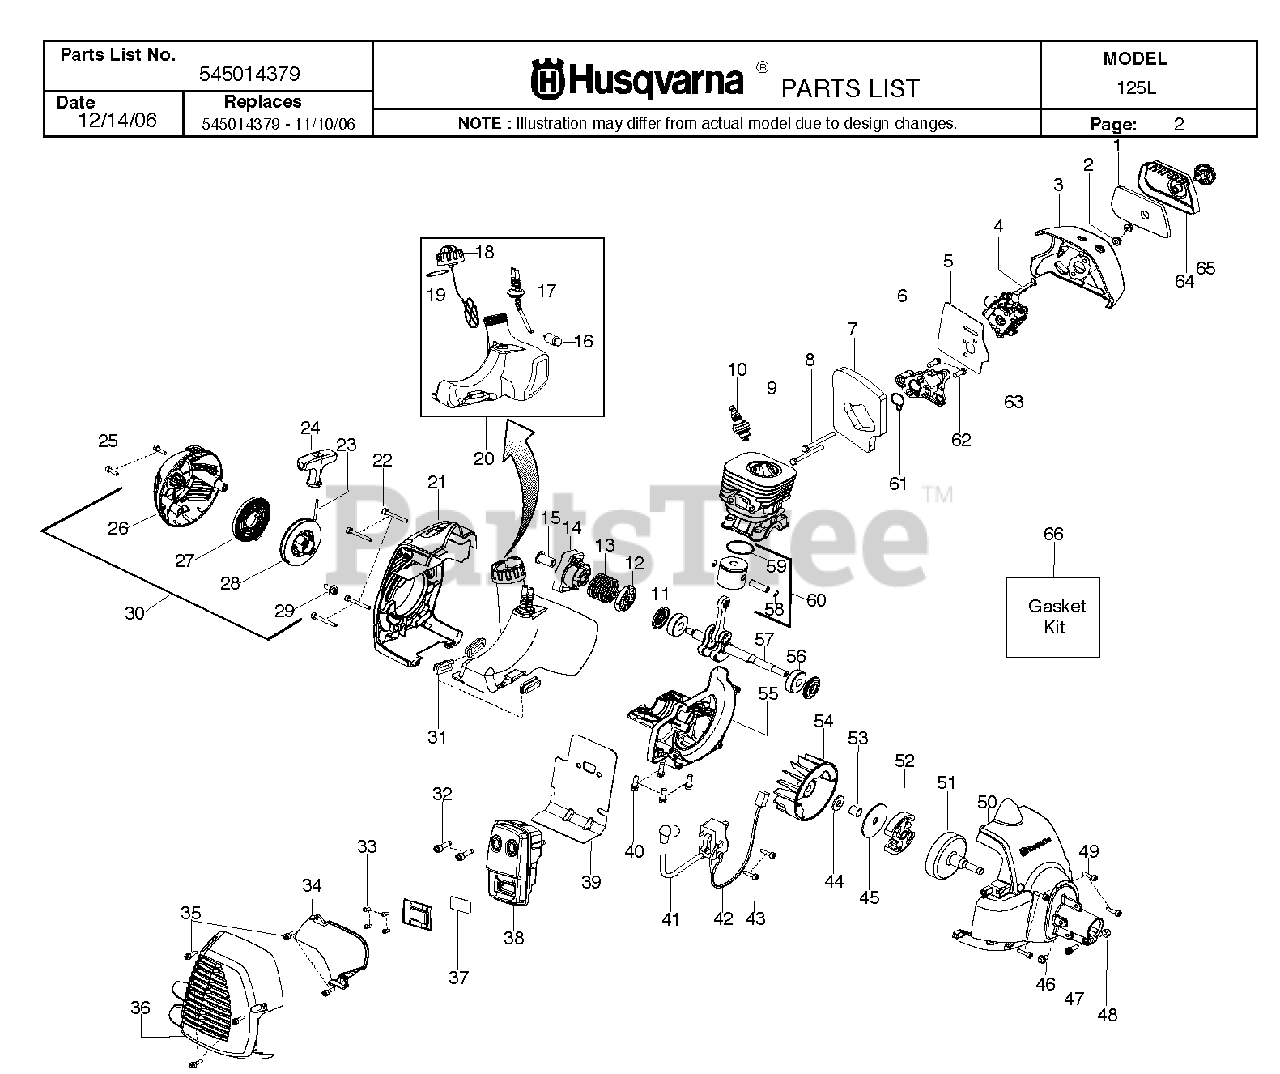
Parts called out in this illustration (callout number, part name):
2	Nut-Carb. Screw
3	Air Box
4	Lever - Choke
5	Kit-Carb. Gasket
6	Adaptor-Carb.
7	Kit-Gasket
9	Cylinder
10	Plug-Spark
11	Kit-Crankshaft seal
12	Washer-Starter
13	Spring-Starter Cup
14	Assy-Starter Cup
15	Coupling-Starter
16	Assy-Fuel Filter
17	Kit-Fuel Line
18	Assy-Cap w/ret.
19	O-ring - Fuel Cap
20	Assy-Fuel Tank
21	Shroud-Rear
24	Handle-Starter
26	Starter Hsg. w/eyelet
27	Kit-Starter Spring
28	Kit-Starter Pulley
30	Assy-Starter Hsg.
31	Isolator-Tank
32	Bolt-Muffler
34	Shield-Heat
36	Guard-Muffler
37	Kit-Spark Arrestor
38	Assy-Muffler
39	Gasket-Paper Metal
42	Assy-Leadwire
45	Washer-Clutch
50	Assy-Fan Housing
51	Assy-Clutch Drum
52	Kit-Clutch Assy.
55	Crankcase-Cast
57	Kit-Crankshaft
58	Retainer-Piston Pin
59	Ring-Piston
60	Kit-Piston
61	Kit-Gasket
63	Kit-Carb.
64	Cover-Air Box
66	Kit-Gasket
